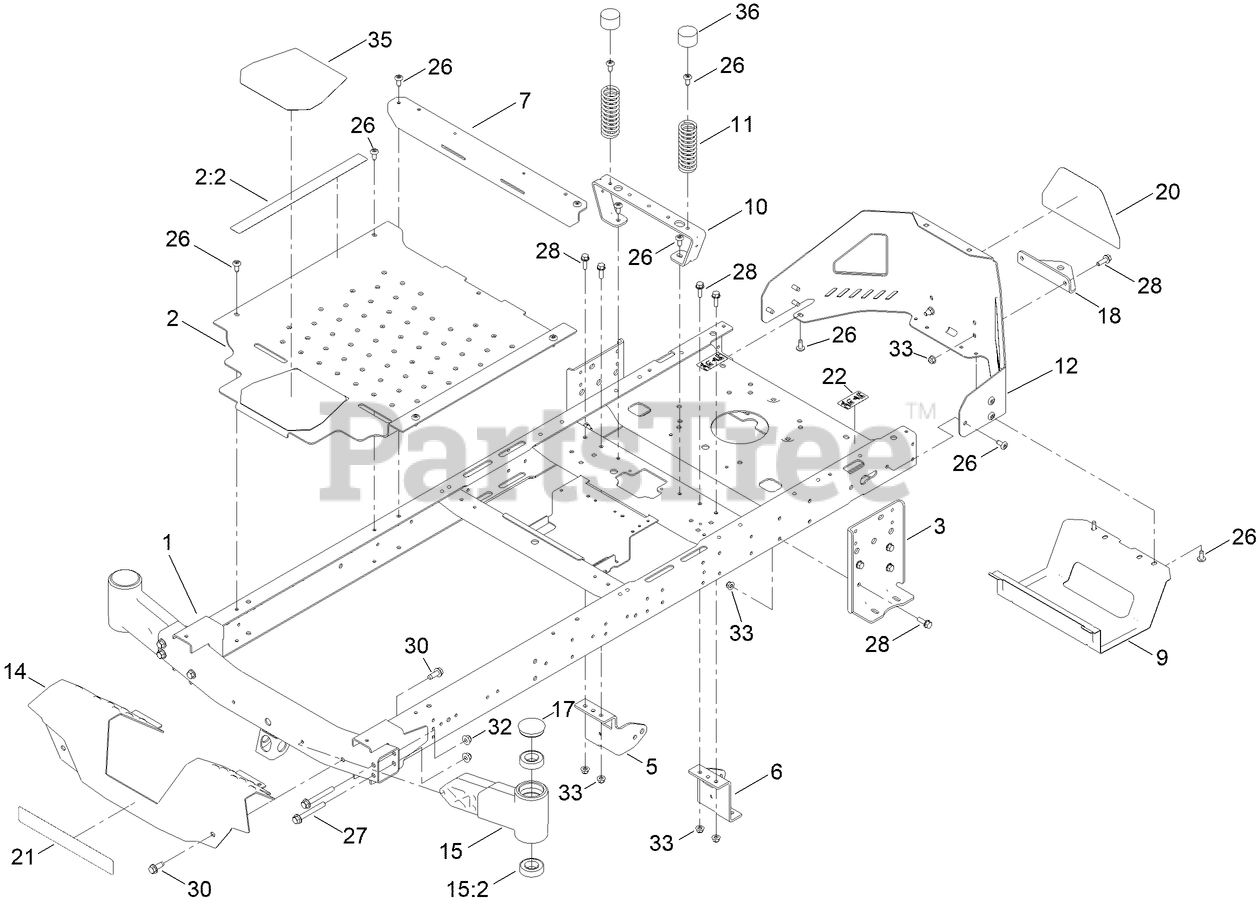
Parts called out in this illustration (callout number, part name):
1	FRAME ASSEMBLY
2	PAN-FLOOR ASM
2:2	DECAL-WARNING
3	PLATE-MOUNT, HYDRO
5	MOUNT-HYDRO, FRONT (RIGHT)
6	MOUNT-HYDRO, FRONT (LEFT)
7	BRACE-CROSS
9	GUARD-MUFFLER
10	SUPPORT-SEAT
11	SPRING-COMPRESSION
12	GUARD-ENGINE
14	FOOTREST
15	AXLE STUB ASM
15:2	BEARING-BALL
17	CAP-GREASE
18	BRACKET-HITCH
20	DECAL-TIMECUTTER
21	DECAL-TIMECUTTER
22	DECAL-BYPASS
27	SCREW-HHF
28	SCREW-HHF
30	SCREW-HWH
32	NUT-HF, NI
33	NUT-HF, NI
35	TREAD-STEP
36	CAP-PROTECTOR
